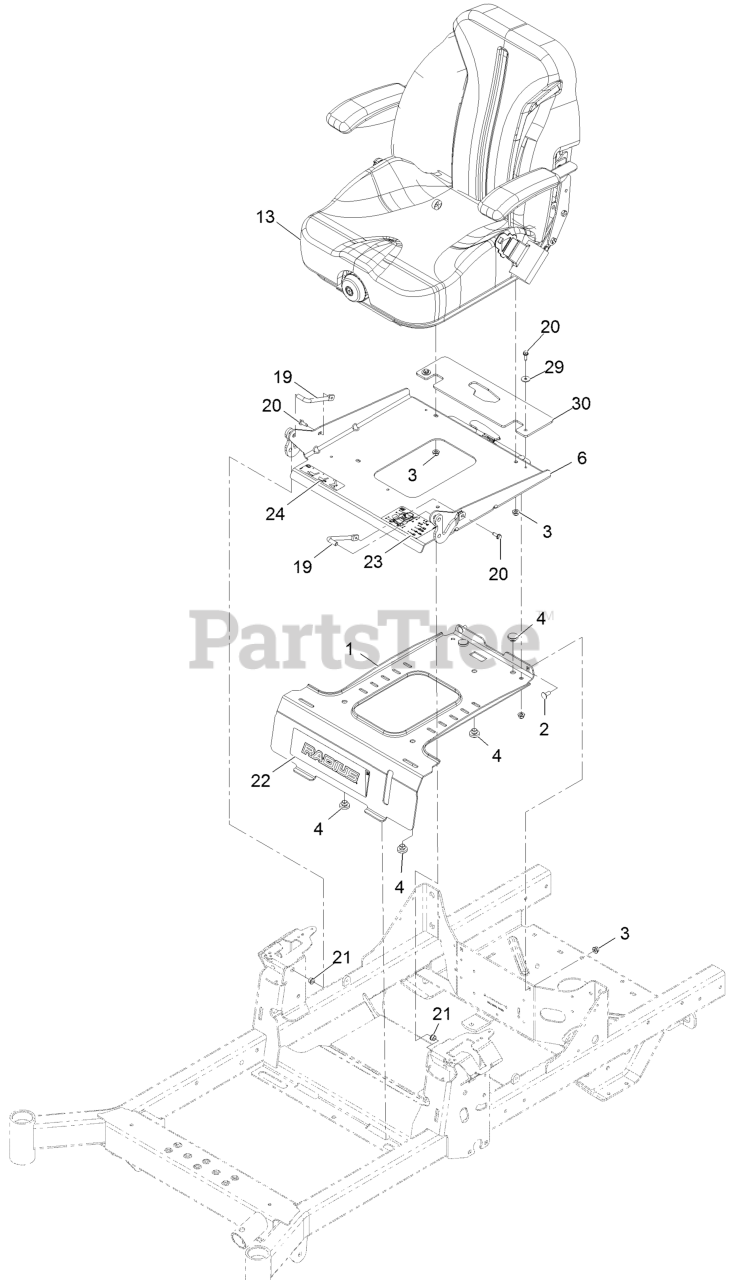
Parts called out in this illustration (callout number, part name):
1	Plate-Retainer, Tank
2	Bolt-Carriage 5/16-18 X 3/4 Short Neck
3	Nut-Nyloc 5/16-18 Flg
4	Bumper-Seat
6	Seat Pan And Latch ASM
13	ASM-Susp Seat
19	Pin-Pivot, Seat
20	Screw-HWH 1/4-20 X 3/4
21	Bushing-Flanged
22	Decal-Radius Logo
23	Decal-Aid, Service
24	Decal-Latch, Seat
30	Guard-Seat, Rubber
